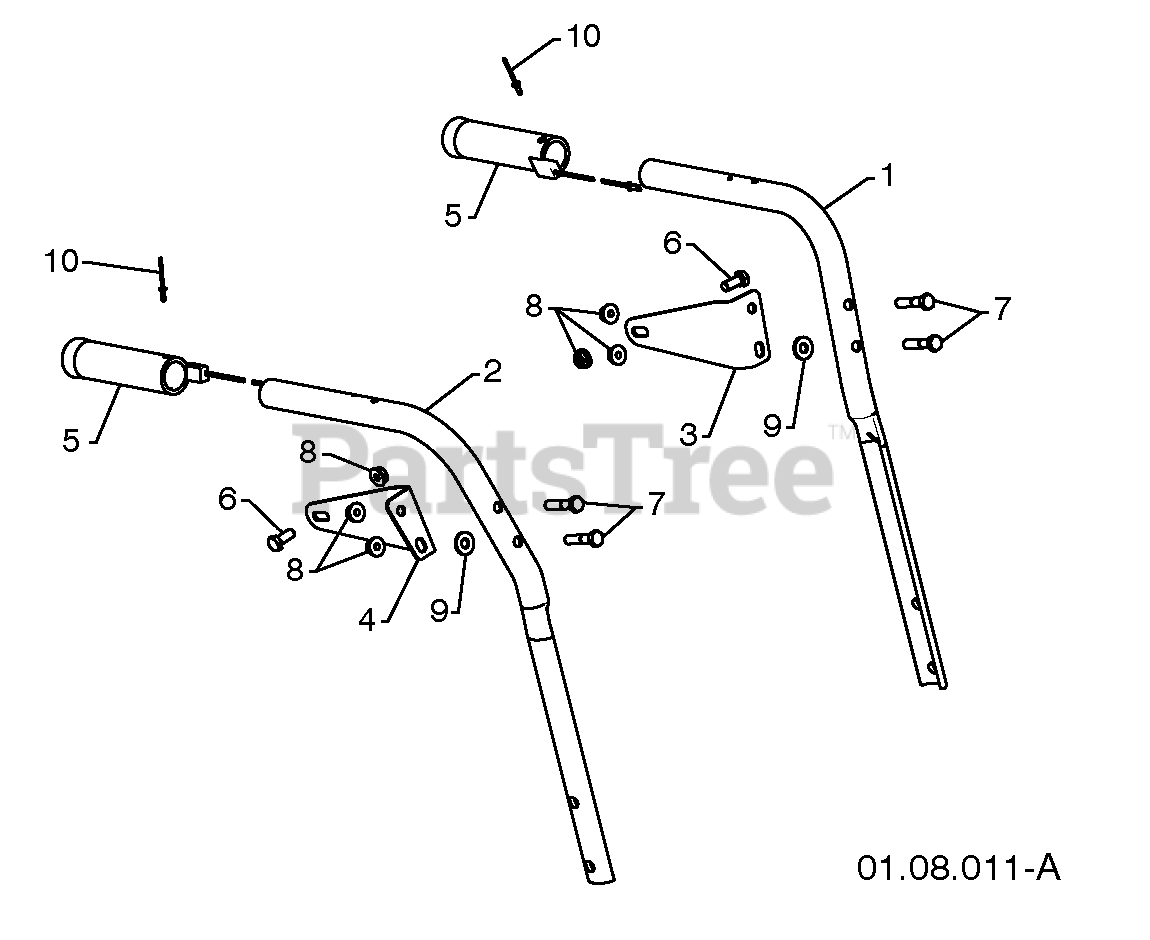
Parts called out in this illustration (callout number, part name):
1	PLOW HANDLE LH
2	PLOW HANDLE RH
3	PANEL BRACKET LH
4	PANEL BRACKET RH
5	HEATED HANDLE GRIP
6	SCREW 5/16-18 X .750
7	SCREW 5/16-18 X 1.50
8	NUT 5/16-18
10	POP RIVET 1/8
